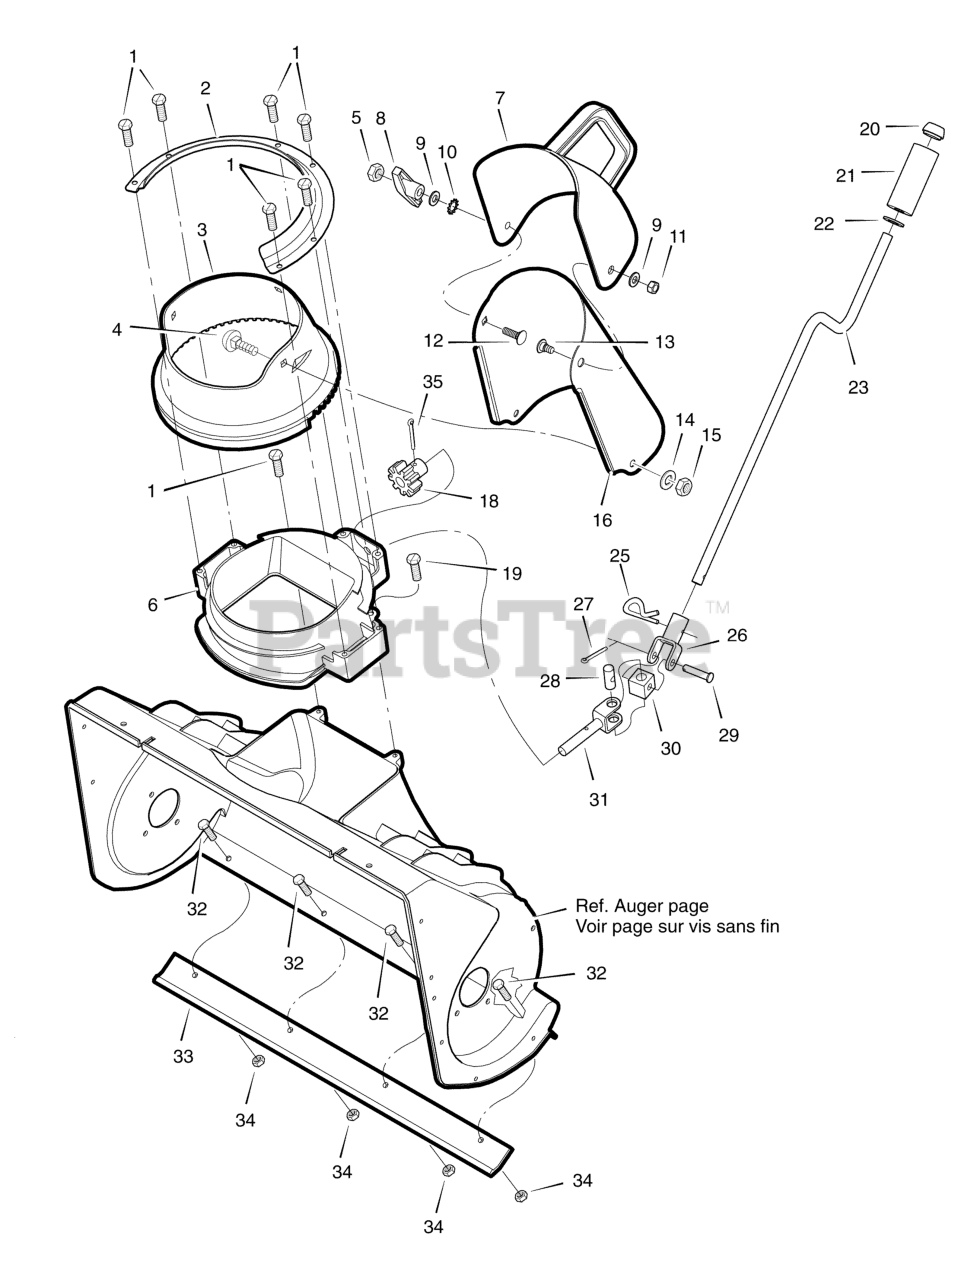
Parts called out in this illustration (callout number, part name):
1	Screw 1/4-14
2	Retainer, Chute Ring
3	Ring, Chute
4	Bolt, Carriage 5/16-18 x .75
5	Nut
6	Neck, Chute
7	Chute, 22" Upper
8	T-Knob
9	Washer
10	Lockwasher, Shakeproof
11	Locknut, Hex 5/16-18
12	Bolt, Carriage 5/16-18
13	Bolt, Upper Chute
14	WASHER, Flat, 13/32
15	Nut
16	Chute, Lower
18	Gear, 9-Tooth
19	Screw, 1/4-14 x .75
20	Nut, Push
21	Knob, Sleeve
22	WASHER, Flat, 13/32
23	Crank, Chute Rotation
25	Pin, Hair
26	Yoke Assembly, Adapter
27	Pin, Cotter
28	Pin, Universal Joint
29	Pin, Clevis
30	Housing, Universal
31	Rod, Lower Crank
32	Screw 1/4-20 x .75
33	Blade, Scraper
34	Locknut, Hex 1/4-20
35	Pin, Cotter
